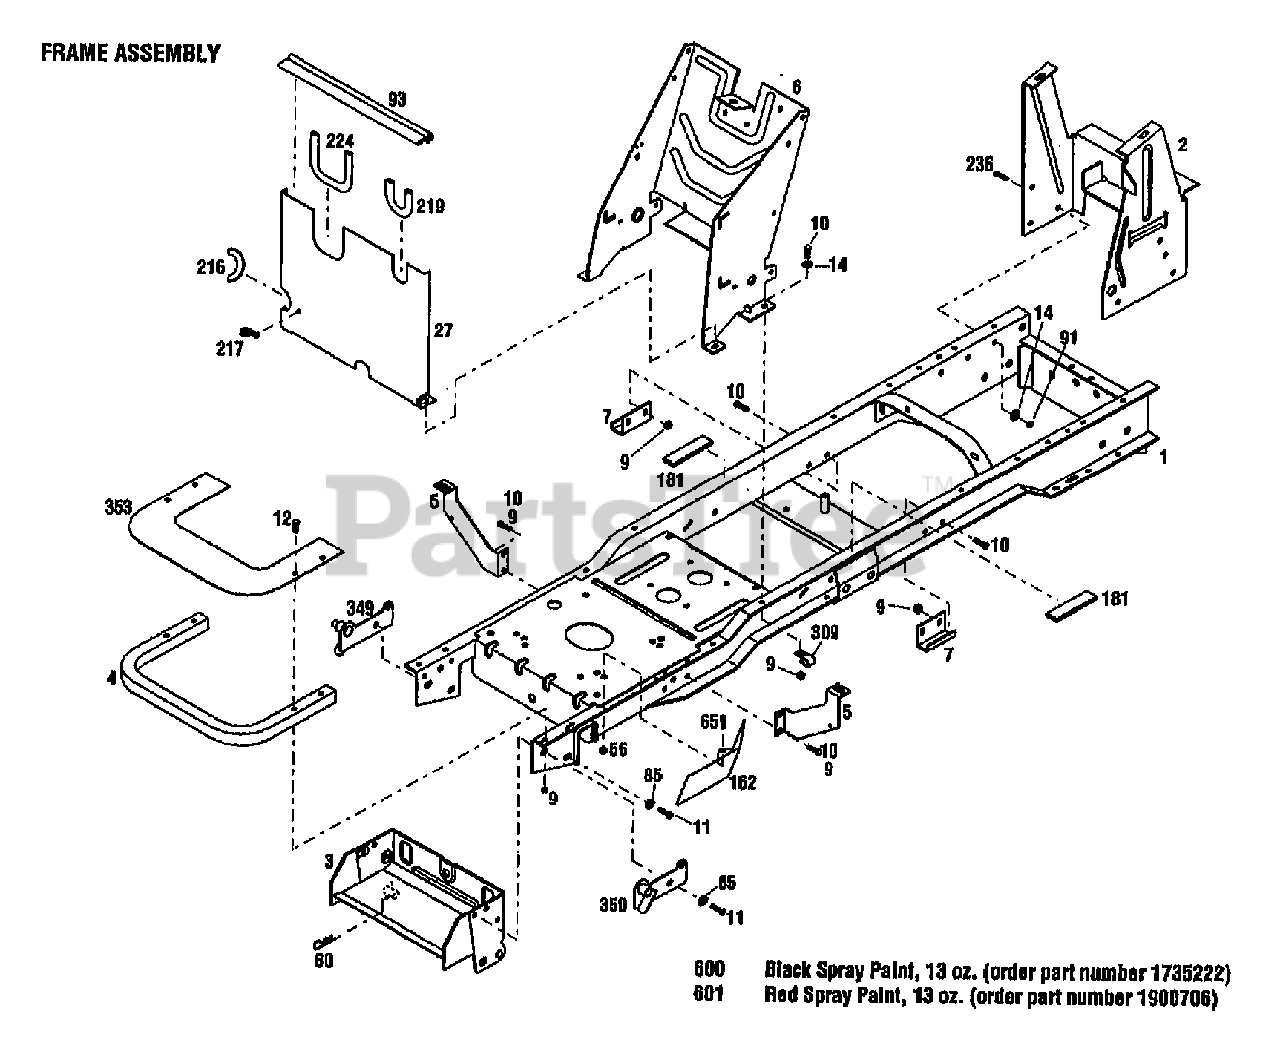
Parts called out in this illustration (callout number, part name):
1	ASSM-FRAME LTX
2	SUPPORT-REAR TANK
3	ASSM-BRKT ATTACHMENT
4	BUMPER-FRONT
5	SUPPORT-FENDER
6	SUPPORT-CONSOLE
9	NUT-HFLK 5/16-18 ZP
10	SCR-HHC 5/16-18X.75 GR 5 ZP
11	SCR-HH 3/8-16X1.0 G5 ZP
12	SCR-HH 5/16-18X1.75
14	WASHER-FLAT 5/16 SAE
27	SHIELD-HEAT
56	NUT-HF/LK 1/4-20 ZP
60	PIN-HITCH .125X2.56 ZP
65	SCR-HH 1/4-20X.625
91	NUT-TOP/LK 5/16-18 ZP
93	GASKET-HEAT SHIELD {13037}
162	SHIELD-HEAT UPPER
216	TRIM {13037}
217	HANGER-CABLE {13037}
219	TRIM {13037}
224	TRIM-HEAT SHIELD {13037}
236	SCR-HFLK 5/16-18X.75 ZP
309	CLIP-J
349	PLATE-PIVOT RH
350	PLATE-PIVOT LH
353	SHIELD-HEAT {13036/037}
600	PAINT-BLACK SPRAY
601	PAINT-RED SPRAYCAN POWDER
